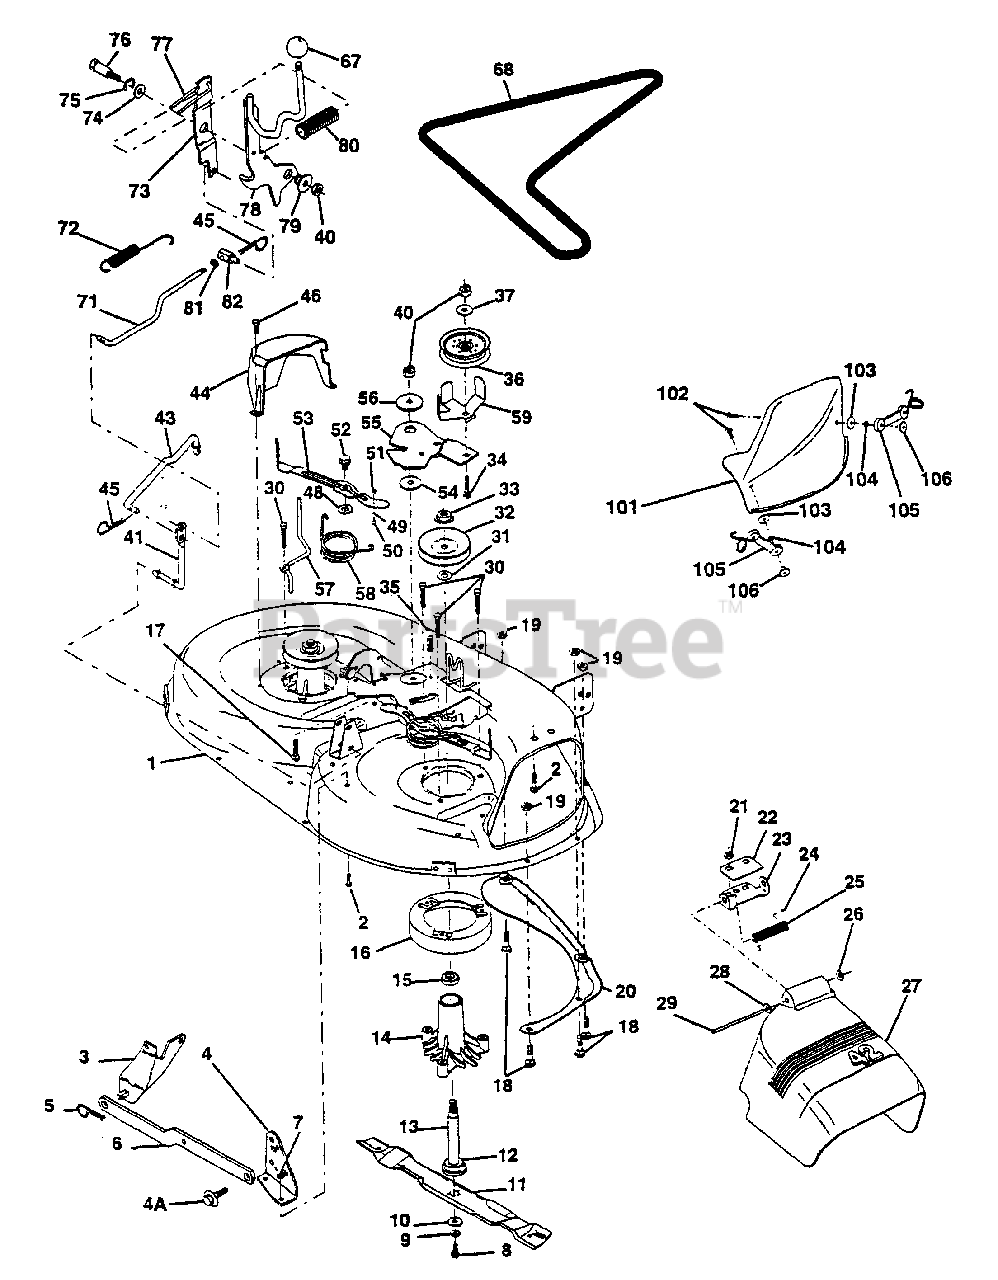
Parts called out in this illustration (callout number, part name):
1	Deck Asm MWR 42" weldment
2	Bolt Rdhd Sqnk 5/16-18unc X3/4
3	Bracket Asm Fr Sway Bar 38/42
4	Bracket Asm Deck 42" sway Bar
4A	Bolt Shoulder
5	Retainer Spring
6	Arm Suspension Rear
7	Locknut-hex W/Ins 5/16-18unc P
8	Bolt 3/8 - 24 X 1.25 Gr 8
9	Washer Lock Hvy 3/8
10	Washer Hard Blade Mower Vented
11	Blade Mower Mulching 42"
12	Bearing Ball #6024 (Mandrel)
13	Shaft Asm W/lower Bearing
14	Housing Mandrel Vented
15	Bearing Ball Mandrel
16	Stripper Mower Vented
17	Bolt Rdhd Sqnk 3/8-16 X 1-1/4
18	Bolt Rdhd Sqnk 5/16-18 X 5/8
19	Locknut-hex W/Ins 5/16-18unc P
20	Baffle Vortex 42
21	Nut Lock Hex W/Ins 5/16-18
22	Stiffener Bracket 42" deck
23	Bracket Deflector Mower 42"
24	Cap Sleeve 80x 112 Blk Mower
25	Spring Torsion Deflector 2 52
26	Nut Push Phos & Oil
27	Shield Deflector Mower 42" Blk
28	Washer 11/32 X 5/8 X 16 Ga
29	Rod Hinge 42" 6 75 Wig
30	Screw Thdrol Hex Head Zinc Mwr
31	Washer Spacer Mower Vented
32	Pulley Mandrel 42"
33	Nut 9/16 Toplock Flng Oil Dip
34	Bolt Rdhd 3/8-16uncxl-3/4 Gr5
35	Fastner Christmas Tree
36	Pulley Idler Flat 3 060
37	Washer 13/32 X 13/16 X 16
40	Nut Lock Hex W/Ins 3/8-16 Unc
41	Rod Pivot W/nibs
43	Rod Clutch Secondary W/nibs
44	Guard Mandrel LH Black
45	Spring Retainer 1" Zinc/cad
46	Screw Hex Thd Cut 1/4-20x5/8 T
48	Washer Hardened Smaller
49	Roller Asm Cam Follower 42" dec
50	Bolt Shldr 10-24 Zinc Gr 5 42"
51	Nut Lock #10-24 Unc
52	Bolt Shoulder 5/16-18 Unc Blkz
53	Arm Asm Pad Brake
54	Washer Hardened
55	Arm Idler 42" mower LT/YT
56	Spacer Retainer Pm Mower
57	Keeper Belt LH Front
58	Spring Torsion Brakes
59	Guard TUV Idler
67	Knob Rd 1/2-13 Plstc Thds Blk
68	V-Belt Mower 42" 82 625
71	Rod Clutch Primary 38/42
72	Spring Return
73	Arm Clutch Secondary
74	Washer 25/32 X 1-5/8 X 16 Ga
75	Ring Klip #t5304-75
76	Bolt Shoulder 3/8-16 Unc 1 44
77	Keeper Spring 4 000
78	Arm Asm Clutch Primary
79	Bushing 747 Od X 794 Lg Brass
80	Spring Clutch Mower 2 750 Zinc
81	Nut Hex Jam 3/8-16
82	Trunnion Adj 94
101	Cover Mulching 42" Black
102	Screw
103	Washer #10
104	Washer Lock #10
105	Latch Asm Bagger
106	Nut Weld
